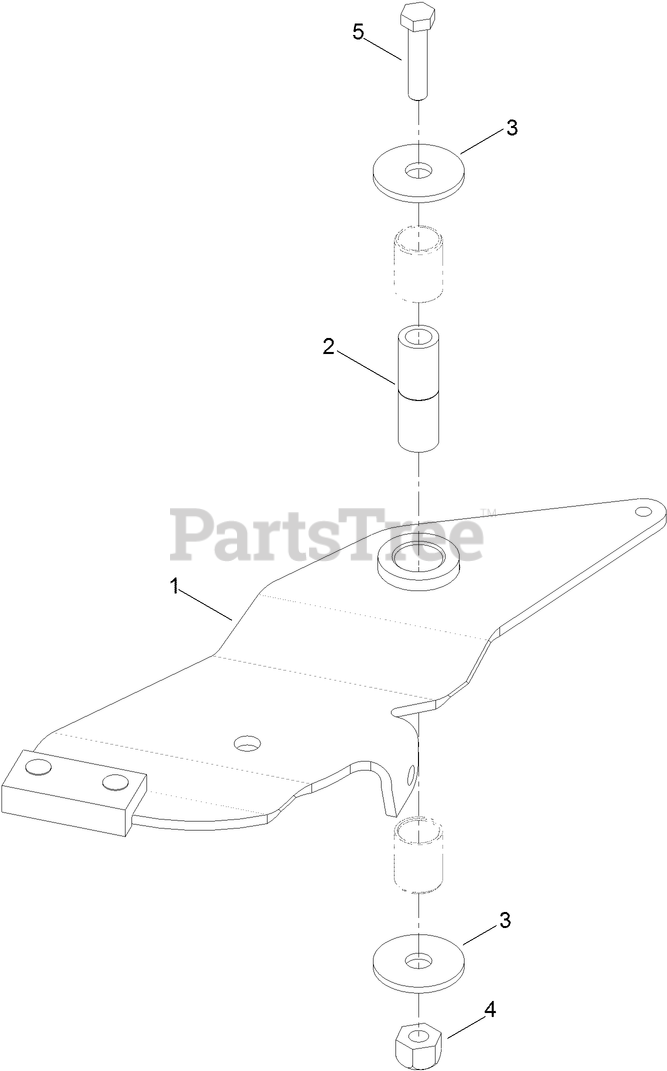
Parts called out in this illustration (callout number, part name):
1	BRAKE ARM ASM
2	Spacer-Brake
3	WASHER-PIVOT
4	NUT-LOCK, NI
5	SCREW-HH
